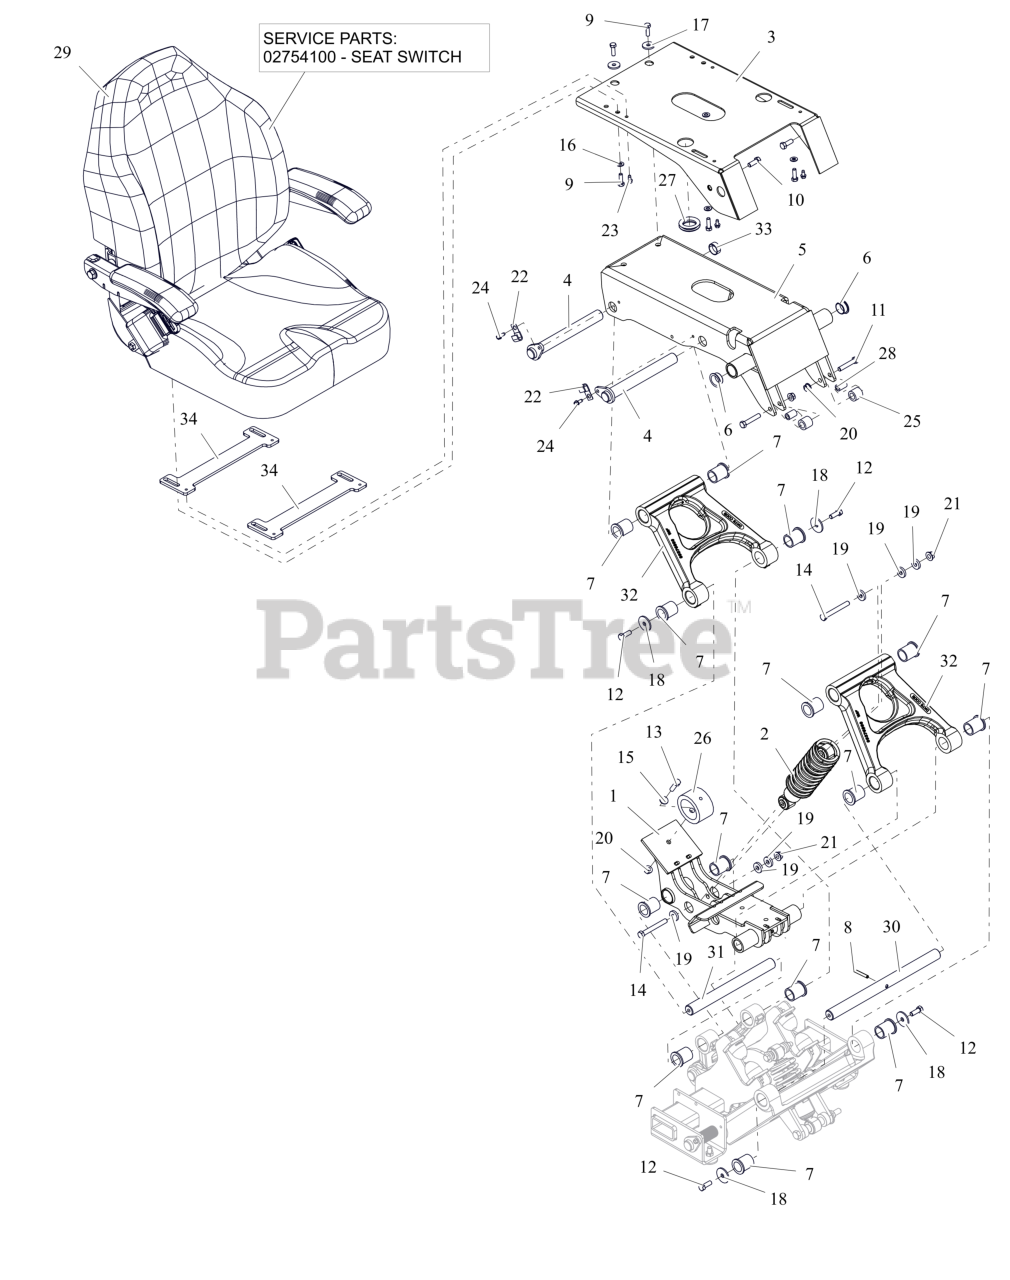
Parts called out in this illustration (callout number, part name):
1	MACHINED, SUSPENSION MID LINK (BLACK)
2	SHOCK, UPPER - TENNECO
3	WLDMT, SEAT MOUNT (RED)
4	WLDMT, UPPER PIVOT SHAFT (RED)
5	WLDMT, SEAT MOUNTING SUPPORT (RED) W/ SAFETY DECALS
6	BSHG-FLG 1.0X1.125X.50X1.375 R
7	BEARING, SINTERED BRONZE FLANGE
8	PIN-ROLL .250X1.75
9	BLT,HEX .31-18X1.00 G5 ZCC
10	BLT,HEX .38-16X1.00 G5 ZCC
11	BLT,HEX .38-16X2.00 G5 ZCC
12	BLT, HEX .38-16X1.00 G8ZCCEP30
13	BLT, HEX .38-16X1.25 G5 ZCC
14	BLT,HEX M10-1.5X80 G10.9 ZCC
15	WSHR,FLT .406X.812X.065 ZCC
16	WSHR,FLT .344X.688X.065 ZCC
17	WSHR, FLT .340X1.125X.135 ZCC
18	WSHR, FLT .380X1.50X.125 ZCC
19	WSHR, FLT .406X1.00X.188 ZCC
20	NUT-LK-CTR-FLG .375-16 GF ZCC
21	NUT, FLG-CTR LK M10-1.50 ZCC
23	SCR-TAP .25-20X.50 HWH ZCC
24	SCR,TAP .25-20X.625 HWH ZCC
25	BUMPER,RUBBER .62X1.0X.88 LG
26	BUMPER, RADIAL (GBR)
27	GROMMET 1.25ID X 1.5OD
28	BUSH.,S.391X.622X.950 ST
29	SEAT, PT600
29	SWITCH- SNAP MTG N.O.
30	SHAFT, PIVOT
31	SHAFT, PIVOT
32	MACHINED, UPPER LINK
33	CAP, 1.000 ID X .375 DEEP
34	SPCR, SEAT MTG (RED)
